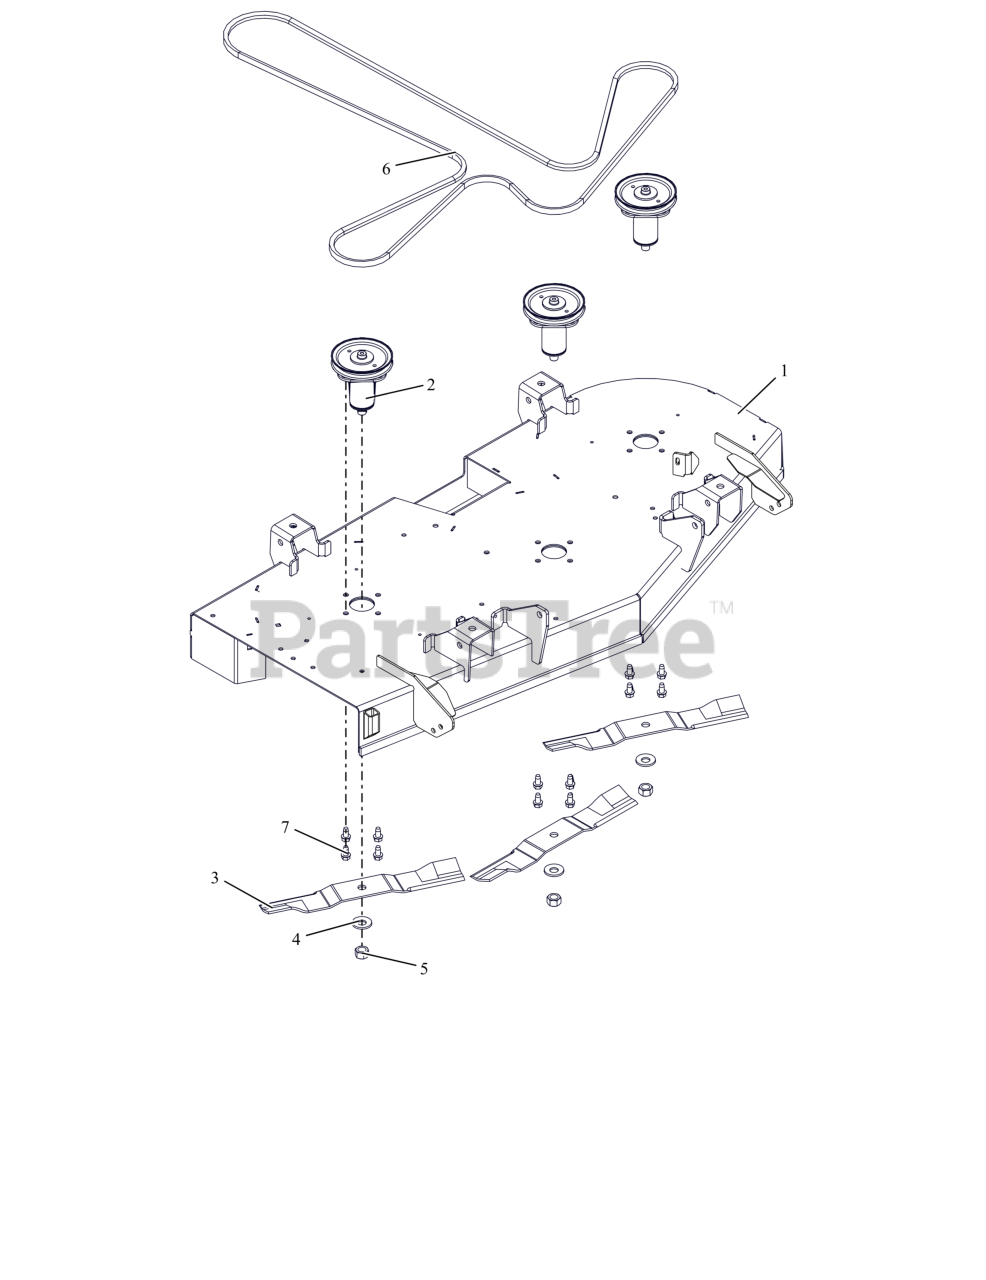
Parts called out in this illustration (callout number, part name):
1	WLDMT, DECK 48"
2	ASM, SPINDLE
3	BLADE, MOWER - 16.19" LG
4	WSHR-BLVL .669X1.535X.138
5	NUT-STD .625-18 ZCC
6	V-BELT, HA-WRAPPED
7	SCR,TAP .375-16X.75 HWH TR ZCC
